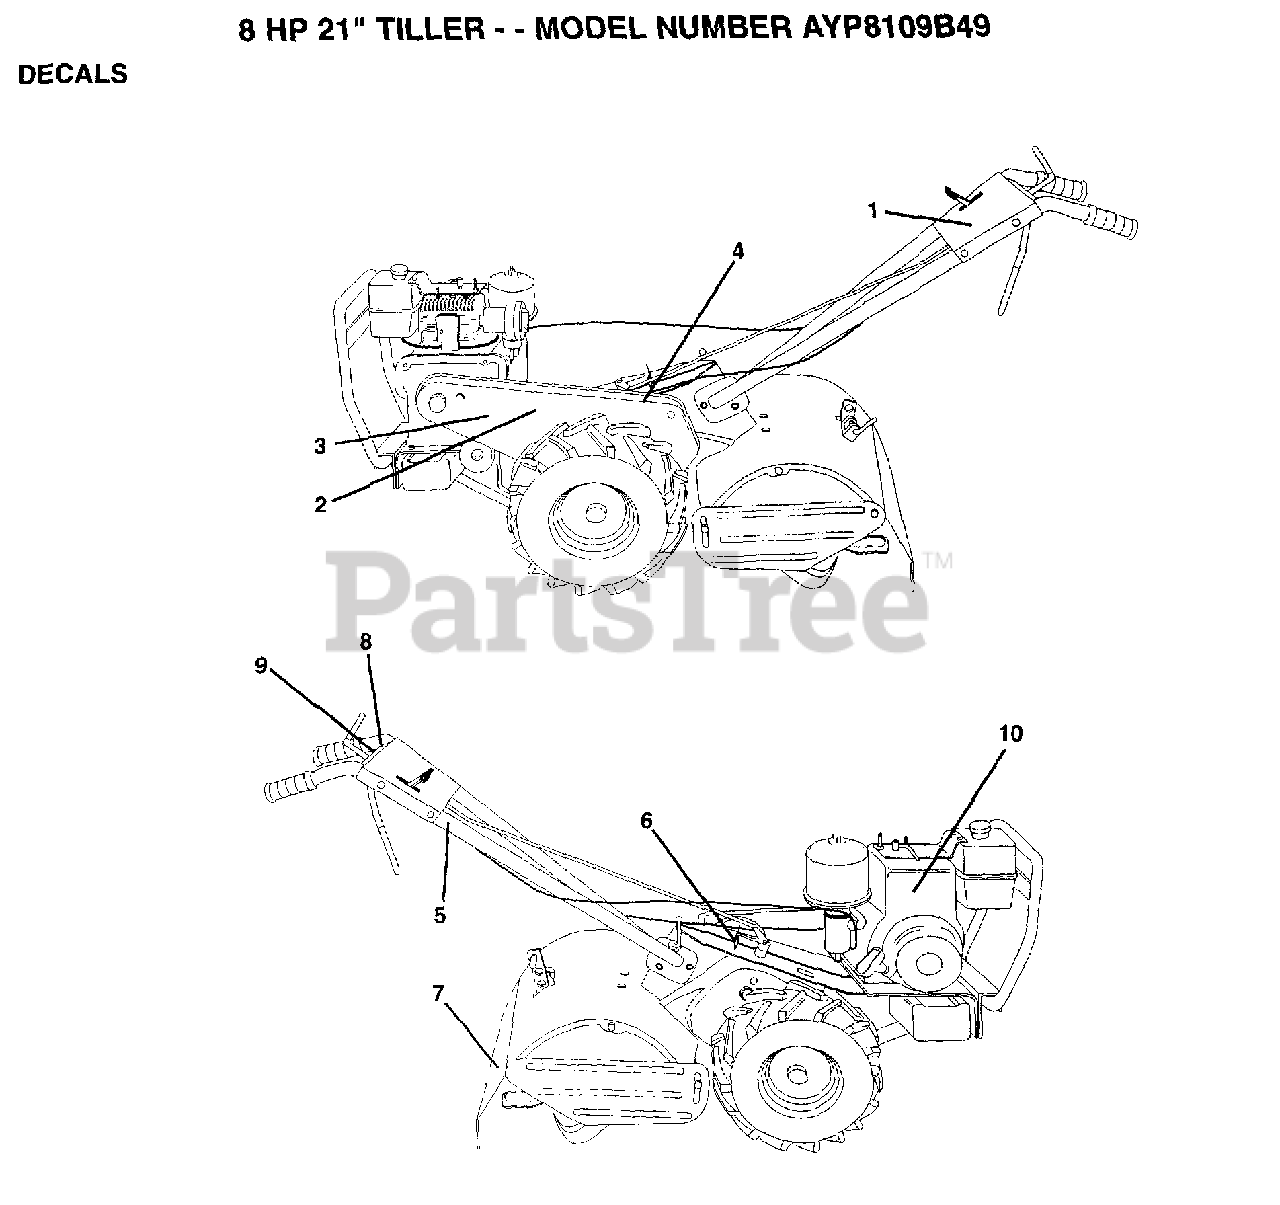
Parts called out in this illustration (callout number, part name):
1	DECAL LOGO CTRL
3	DECAL LOGO GUARD
5	DECAL TI
6	DECAL.SHIFT.IND.
7	DECAL TI
10	DECAL, BRIGGS & STRATTON
